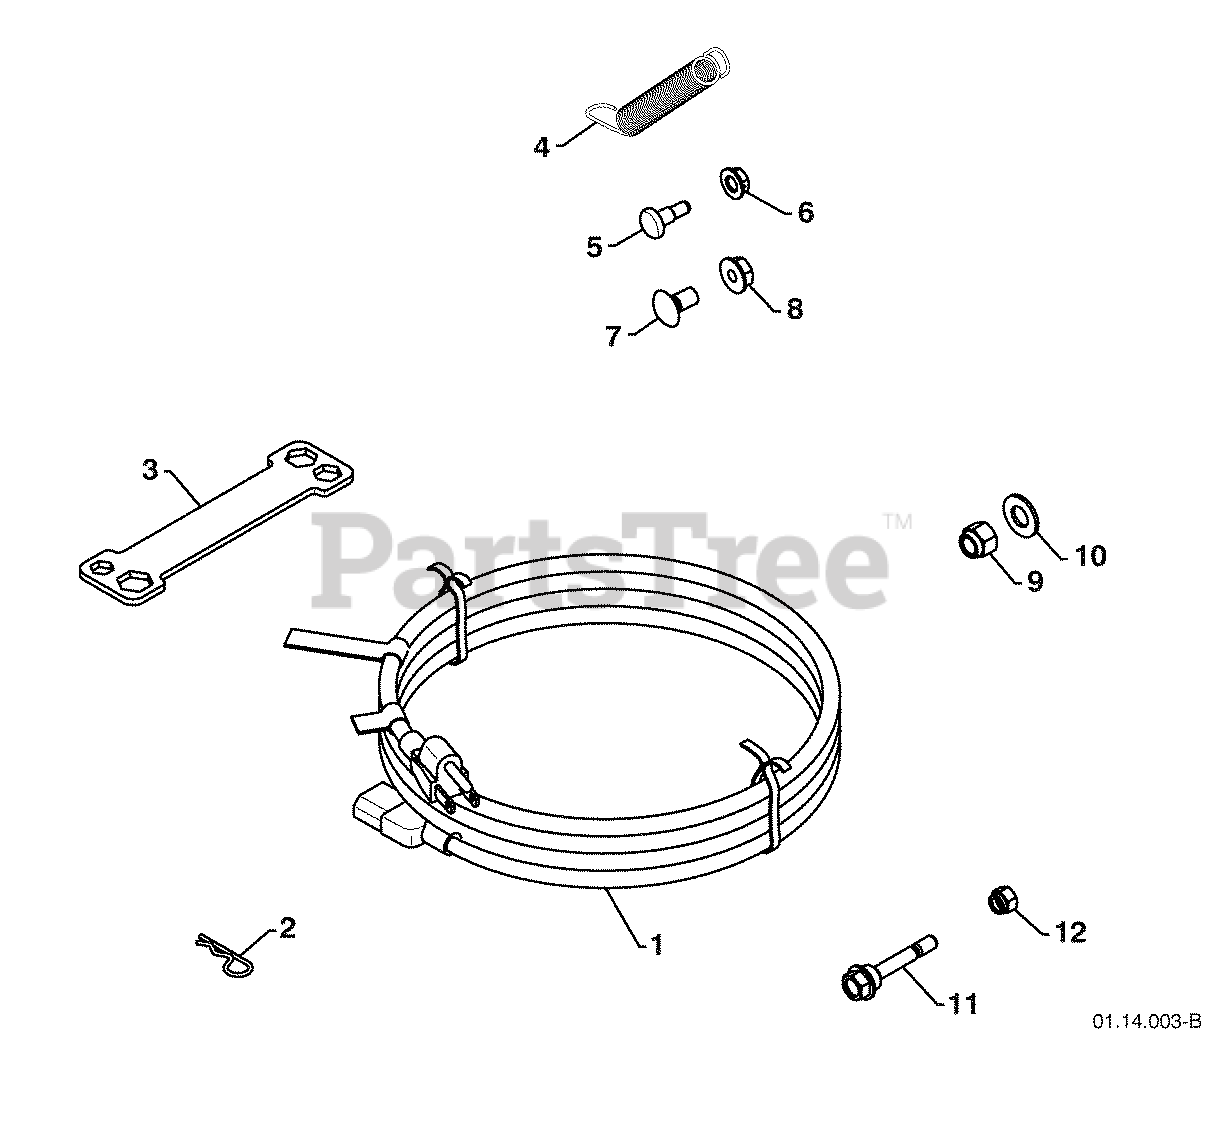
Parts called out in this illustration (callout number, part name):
1	POWER CORD
2	RETAINER PIN
4	REMOTE SPRING
5	SHOULDER BOLT 1/4-20
6	LOCKNUT 1/4-20
7	CARRIAGE BOLT 5/16-18 X 5/8
8	LOCKNUT 5/16-18
9	LOCKNUT 3/8-16
10	WASHER 3/8
11	SHEAR BOLT 1/4-20 X 1-13/16
12	LOCKNUT 1/4-20
